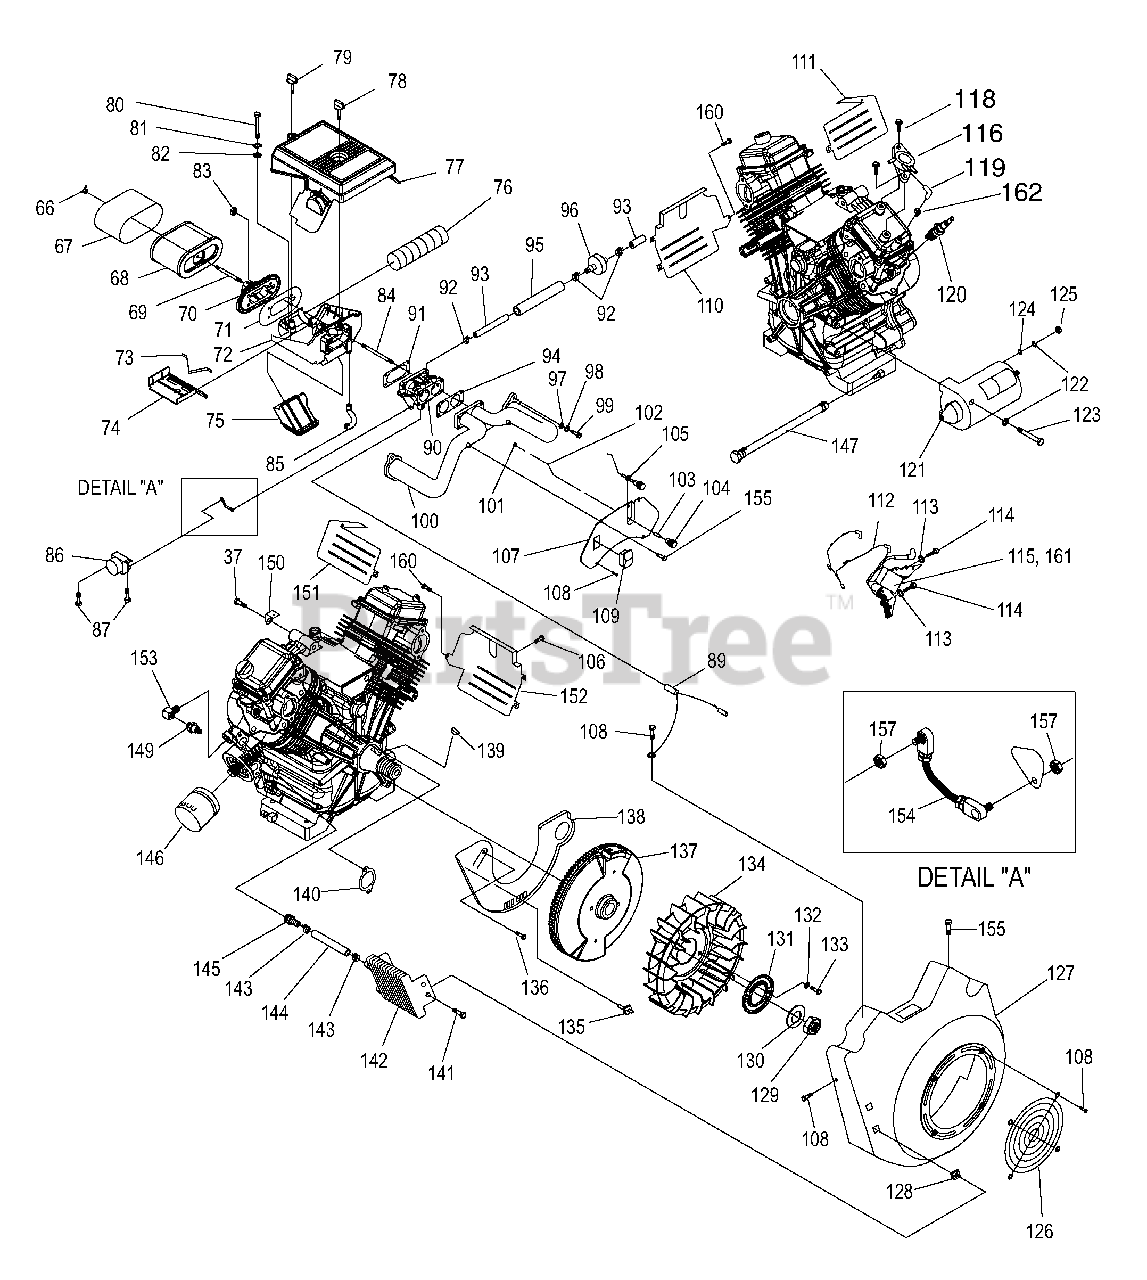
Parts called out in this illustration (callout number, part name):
66	WINGNUT, AIRBOX
67	PRECLEANER, AIR
68	ELEMENT, AIR CLEANER
69	STUD M6-1.0 X 73
70	ADAPTOR, SPIT BACK
71	GASKET, SPITBACK
72	BASE, AIRBOX
73	SPRING, WINTER/SUMMER VALVE
74	VALVE, SUMMER / WINTER
75	SNORKEL, AIR INTAKE
76	TUBE, HEAT RISER 50.8 I.D.
77	COVER, AIRBOX
78	KNOB, AIRBOX 17mm
79	KNOB, AIRBOX 95MM
80	SCREW HHC M6-1.0 X 35
81	WASHER LOCK M6-1/4
82	WASHER FLAT 1/4
83	NUT, HEX FLANGE WHIZ M6-1.0
84	STUD, METRIC
85	HOSE, BREATHER
86	CONTROLLER ASSEMBLY
87	SCREW HHTT M5-0.8 X 10
89	ASSEMBLY, WIRE
90	CARBURETOR (GT-990)
91	GASKET, CARB TO SPACER (GT-990)
92	CLAMP HOSE BAND 1/4
93	HOSE 1/4 ID
94	GASKET, MANIFOLD TO CARB (GT-990)
95	SLEEVING, FLEXO HW 3/4 3"
96	FILTER, FUEL
97	WASHER FLAT M8
98	WASHER LOCK M8
99	SCREW SHC M8-1.25 X 30
100	MANIFOLD, INTAKE
101	NUT HEX M3-0.5
102	ROD, SUMMER / WINTER VALVE
103	BUSHING, MINI CONTROL PANEL
104	KNOB, CONTROL SUMMER / WINTER
105	CHOKE ASSEMBLY
106	SCREW TAPTITE M5-0.8 X 8 ZP
107	PANEL, CONTROL FACE PLATE
108	SCREW TAPTITE M6-1.0X 10 YELLOW CHROME
109	SWITCH ROCKER
110	WRAPPER, LOWER CYLINDER 2
111	WRAPPER, UPPER CYLINDER 2
112	ASSEMBLY, GROUND WIRE
113	WASHER LOCK M6-1/4
114	SCREW TAPTITE M6-1.0 X 25 BP
115	ASSY, IGN COIL W/DIODE NO ADV
116	PUMP, IMPULSE
118	SCREW, HHFCS M6-1.0 X 16 G8.8
119	ELBOW, RUBBER 90 DEG. GASOLINE
120	SPARKPLUG, CHAMPION RC14YC
121	STARTER, DELCO REMY SD80
122	WASHER LOCK M8-5/16
123	SCREW HHC M8-1.25 X 85 G8.8
124	WASHER, FLAT M8
125	NUT, HEX M8-1.25 YELLOW ZINC
126	GUARD,FAN
127	HOUSING, BLOWER GAS COOLER
128	NUT, GROMMET 1/4 PLUG
129	NUT,HEX M24
130	WASHER, M24
131	PLATE, FAN
132	WASHER SHAKEPROOF INT M8 SS
133	SCREW HHC M8-1.25 X 12 G8.8
134	FAN, NYLON
135	ASSY,GROUND WIRE CONNECTOR
136	SCREW TAPTITE M6-1X10 YELLOW CHROME
137	FLYWHEEL ASSEMBLY
138	PLATE, BACKING GT990 W/OIL COOL
139	KEY, WOODRFF 4 X 19D
140	GASKET, MANIFOLD / PORT
141	PLASTITE,1/4-15 X 3/4
142	COOLER, OIL
143	CLAMP, HOSE OETIKER 16.5mm
144	HOSE, 3/8" I.D. X 6" LONG
145	BARBED STR 1/4NPT X 3/8
146	OIL FILTER
147	ASSEMBLY, OIL DRAIN HOSE
149	SWITCH, OIL PRESS
150	BRACKET, AIRBOX SUPPORT
151	WRAPPER, UPPER CYLINDER 1
152	WRAPPER, LOWER CYLINDER 1
153	BRASS ST ELBOW 1/4 NPT
154	ASSY, ROD, GOV. STEPPER MOTOR
155	SCREW HHHC M6-1.0 X12
157	NUT, LOCK HEX M3-0.5 (GT-990)
160	SCREW HHFC M6-1.0 X 10mm
161	ASSY, IGN COIL W/DIODE NO ADV
162	CLAMP, HOSE BAND GREEN
